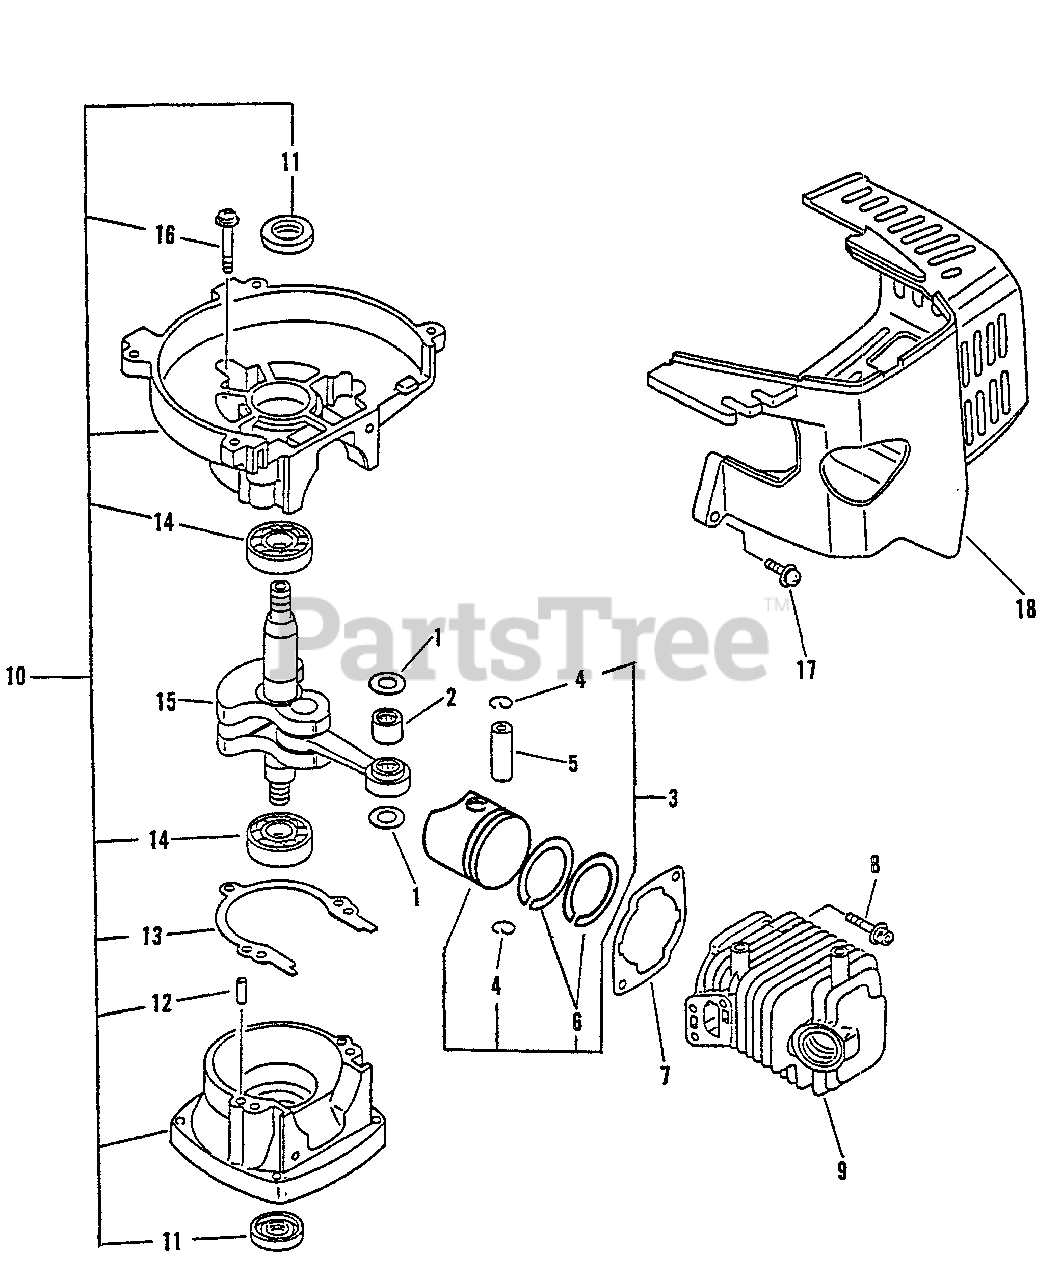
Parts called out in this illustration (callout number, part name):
2	BEARING, NEEDLE - 8
3	PISTON KIT
4	RING, RETAINING
5	PIN, PISTON
6	RING, PISTON
7	GASKET, CYLINDER
8	SCREW - 5X22
9	CYLINDER
10	CRANKCASE KIT
11	SEAL, OIL
12	PIN - LOCATING
13	GASKET, CRANKCASE
14	BEARING, BALL - 6201
15	CRANKSHAFT ASSY
16	SCREW - 5X28
17	SCREW - 4X22
18	COVER, ENGINE
